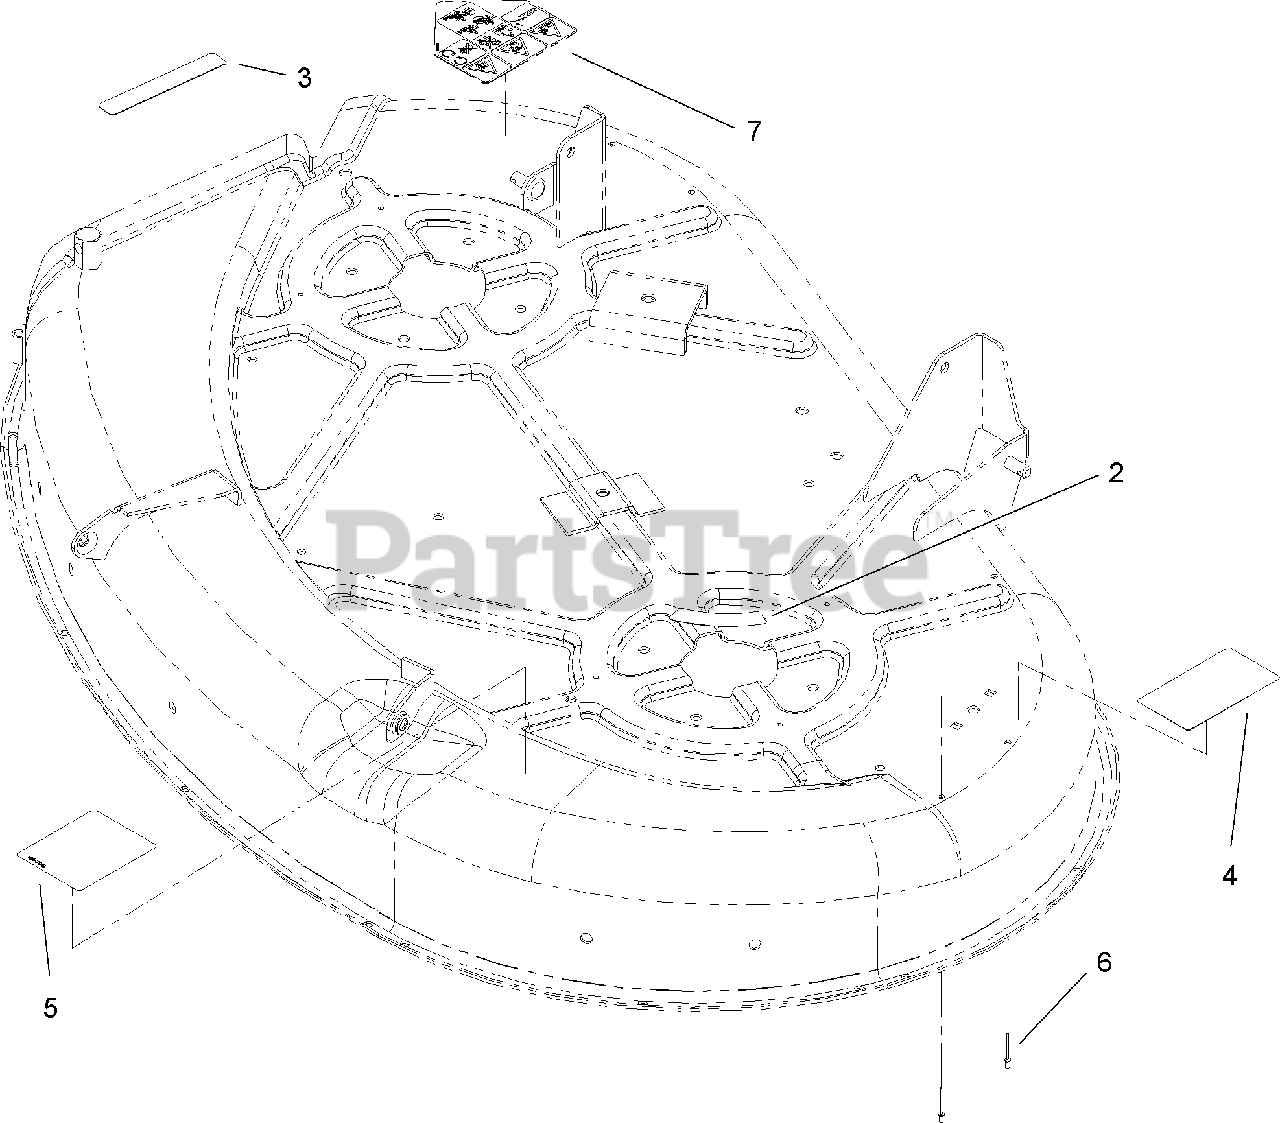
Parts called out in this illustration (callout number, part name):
2	DECAL-SHIELD, DANGER
3	DECAL-DANGER
4	DECAL-DANGER
5	DECAL-ROUTING, BELT
6	RIVET-POP
7	DECAL-DANGER, SHIELD
